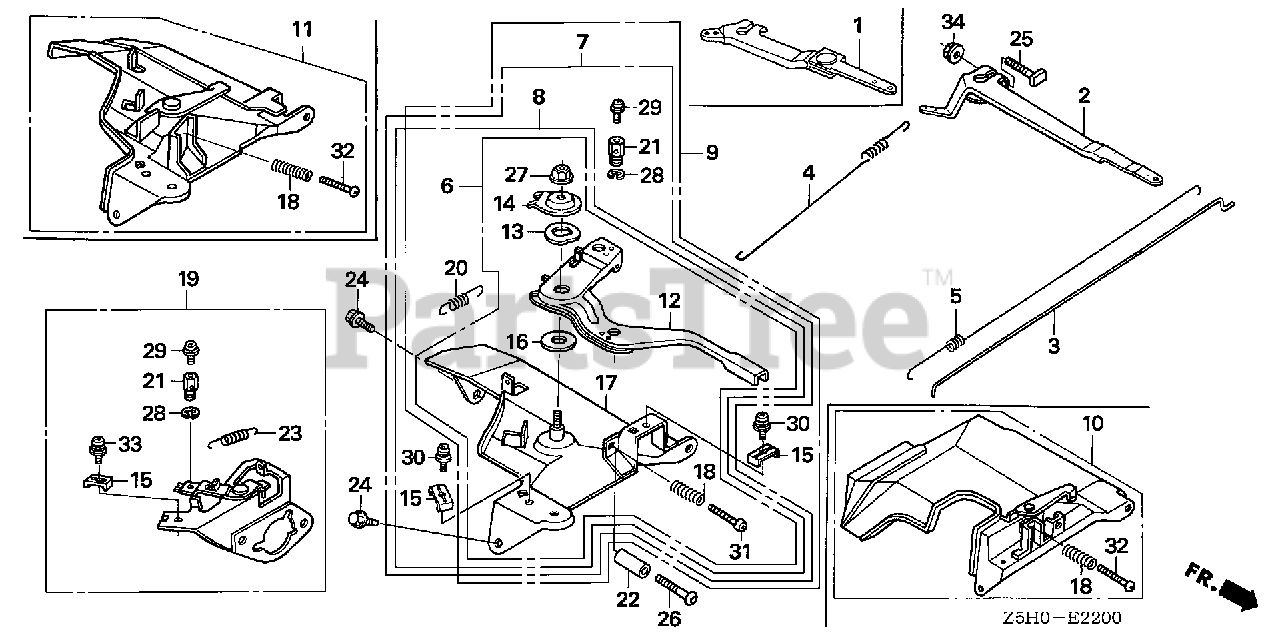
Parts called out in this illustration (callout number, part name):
2	ARM, GOVERNOR
3	ROD, GOVERNOR
4	SPRING, GOVERNOR (L=145.0MM) (WIRE DIAMETER 1.0MM)
5	SPRING, THROTTLE RETURN
8	CONTROL ASSY. (REMOTE)
12	LEVER, CONTROL
13	SPRING, LEVER
14	WASHER, CONTROL LEVER
15	HOLDER, CABLE
16	SPACER, CONTROL LEVER
17	BASE, CONTROL
18	SPRING, CONTROL ADJUSTING Use from Engine SN 2327377.
20	SPRING, CABLE RETURN
24	BOLT, FLANGE (6X12) (CT200)
25	BOLT, GOVERNOR ARM
27	NUT, SELF-LOCK (6MM)
30	SCREW, PAN (5X16)
31	SCREW, PAN (5X28)
34	NUT, FLANGE (6MM)
